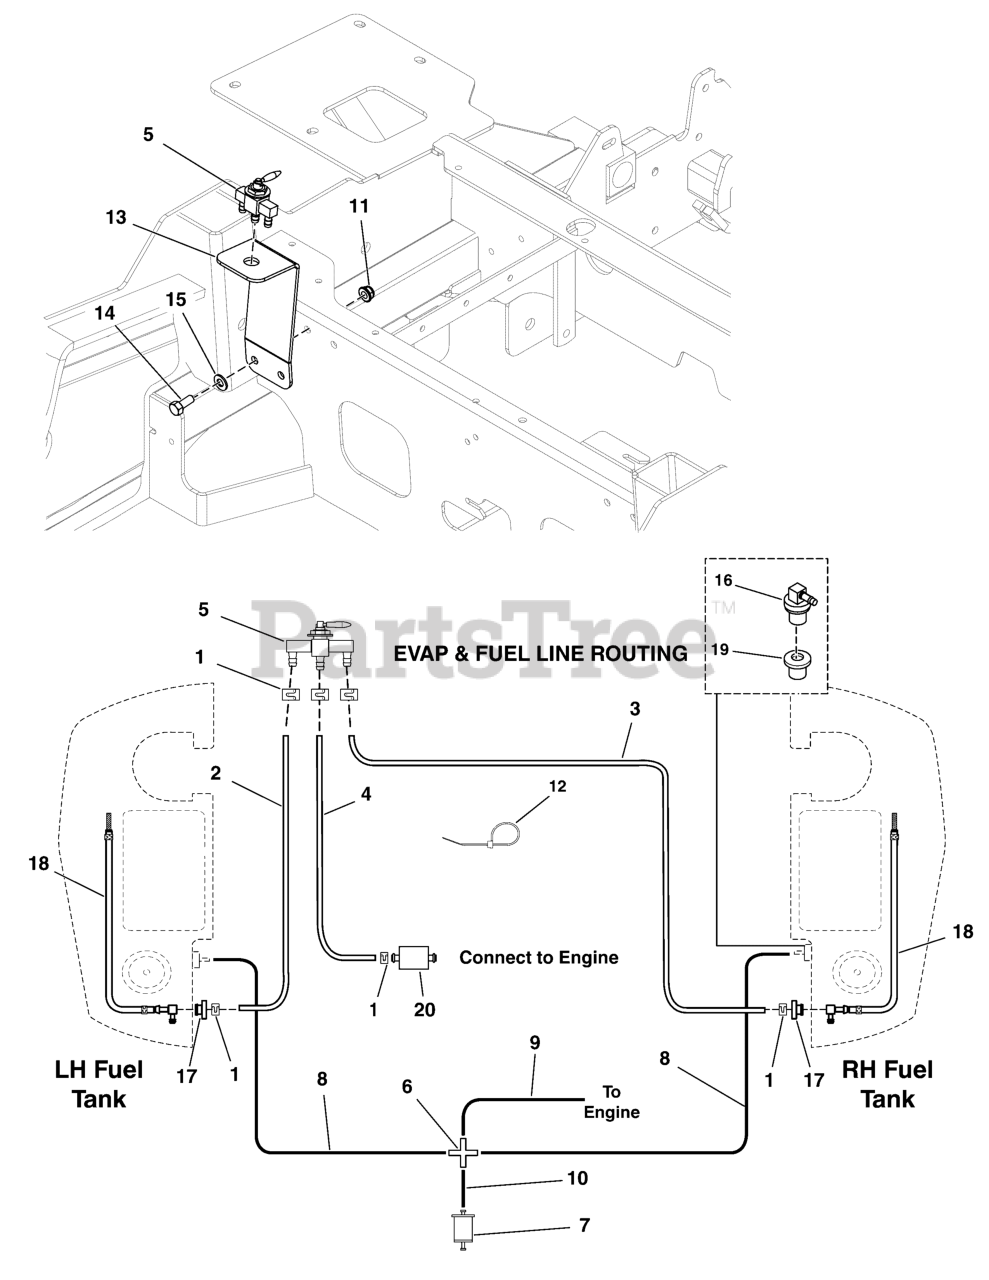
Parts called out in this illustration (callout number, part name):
1	CLAMP, Hose
2	HOSE, 1/4" FUEL, 14.50"
3	HOSE, 1/4" FUEL, 28.50"
4	HOSE, 1/4" FUEL, 12.50"
5	VALVE, FUEL STRAIGHT, OUTLET
6	FITTING, BARBED CROSS, 3/16" BLK NYLON
7	FILTER, FUEL
8	HOSE, VAPOR, 5MM ID, 25.50 LG
9	HOSE, VAPOR, 5MM ID, 19.00 LG
10	HOSE, VAPOR, 5MM ID, 3.00 LG
11	NUT, 5/16-18 HEX NYLOCK FLANGE NUT
12	TIE, SELF-LOCKING, 12"
13	BRACKET, FUEL VALVE, IS2100 - BLK
14	BOLT, 5/16-18 X 3/4 GD5
15	WASHER, 5/16" SAE
16	REMOTE VENT ASSEMBLY
17	BUSHING-FUEL TANK RED RUBBER
18	PICKUP TUBE ASSEMBLY, FUEL LINE (SV)
19	GROMMET (SV)
20	FUEL FILTER (SV)
